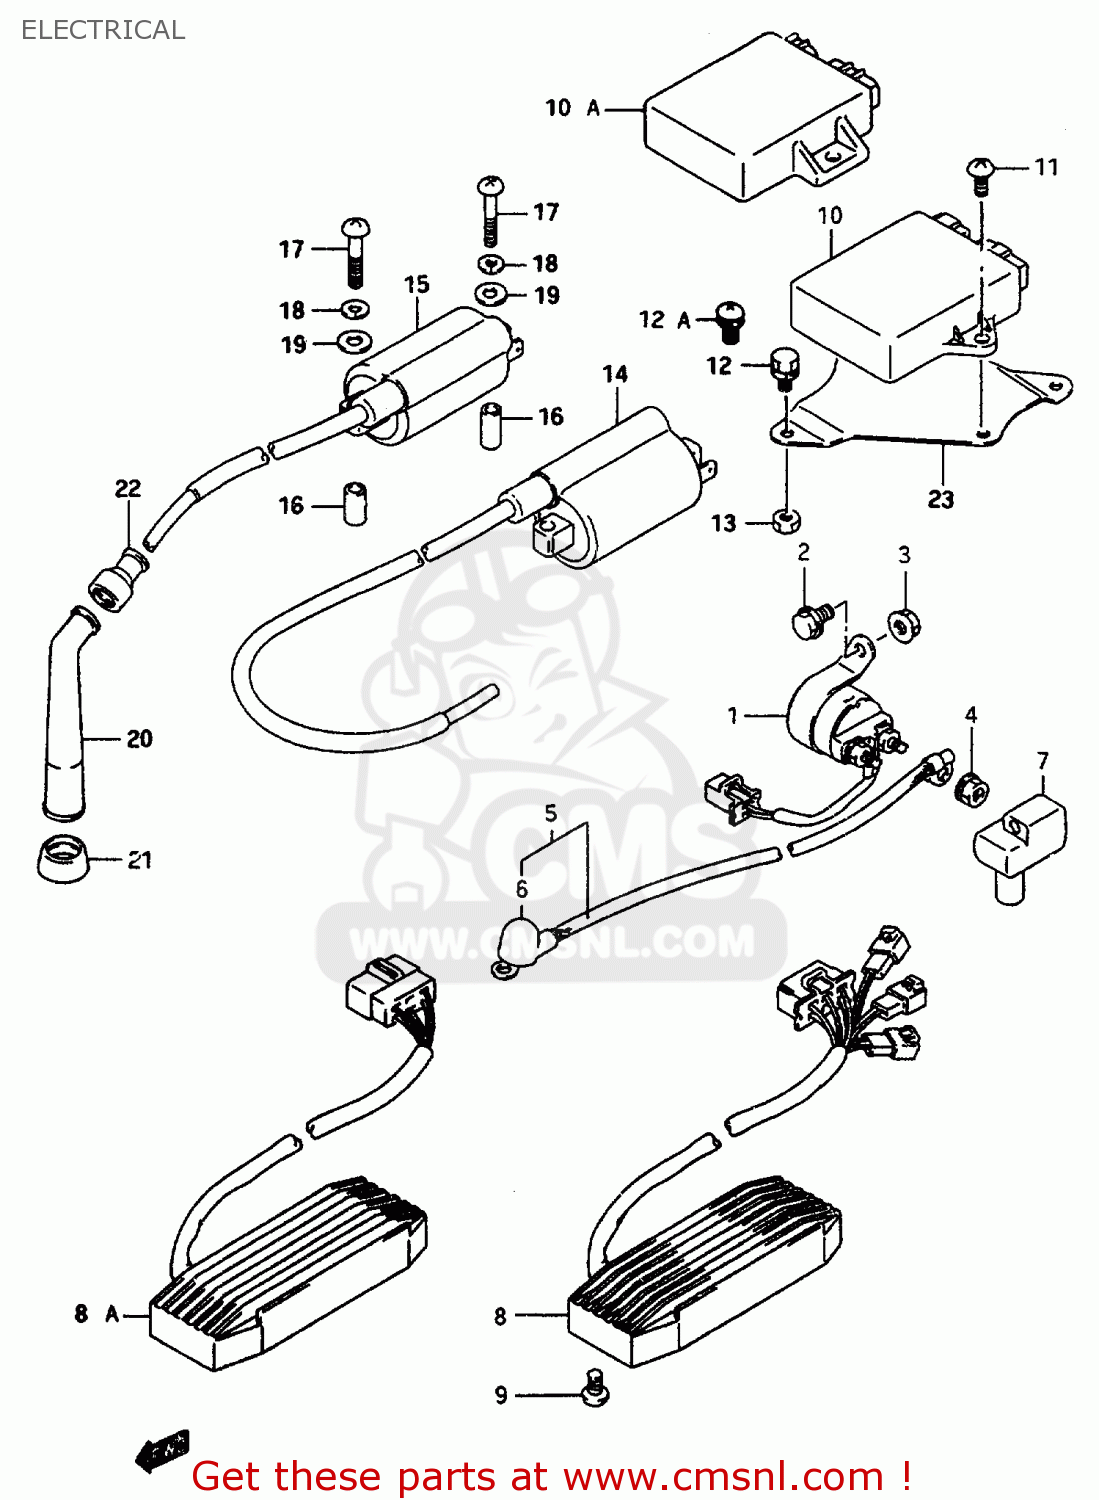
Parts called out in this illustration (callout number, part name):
1	RELAY ASSY,STARTING MOTOR
2	BOLT
3	NUT
4	NUT
5	WIRE,STARTER MOTOR LEAD
6	CAP,STARTER MOTOR LEAD
7	CAP,STARTER RELAY
8	RECTIFIER ASSY
8A	RECTIFIER ASSY
9	BOLT
10	IGNITER UNIT ASSEMBLY
10A	IGNITOR ASSY
11	SCREW 6X12
12	BOLT
12A	BOLT
13	NUT
14	COIL ASSY,IGNITION
15	COIL ASSY,IGNITION
16	SPACER(6.4X10X19)
17	SCREW (5X38)
18	LOCK,WASHER
19	WASHER
20	CAP,SPARK PLUG
21	SEAL,SPARK PLUG CAP
22	SEAL,HIGH TENSION CORD
23	PLATE,IGNITOR FITING
